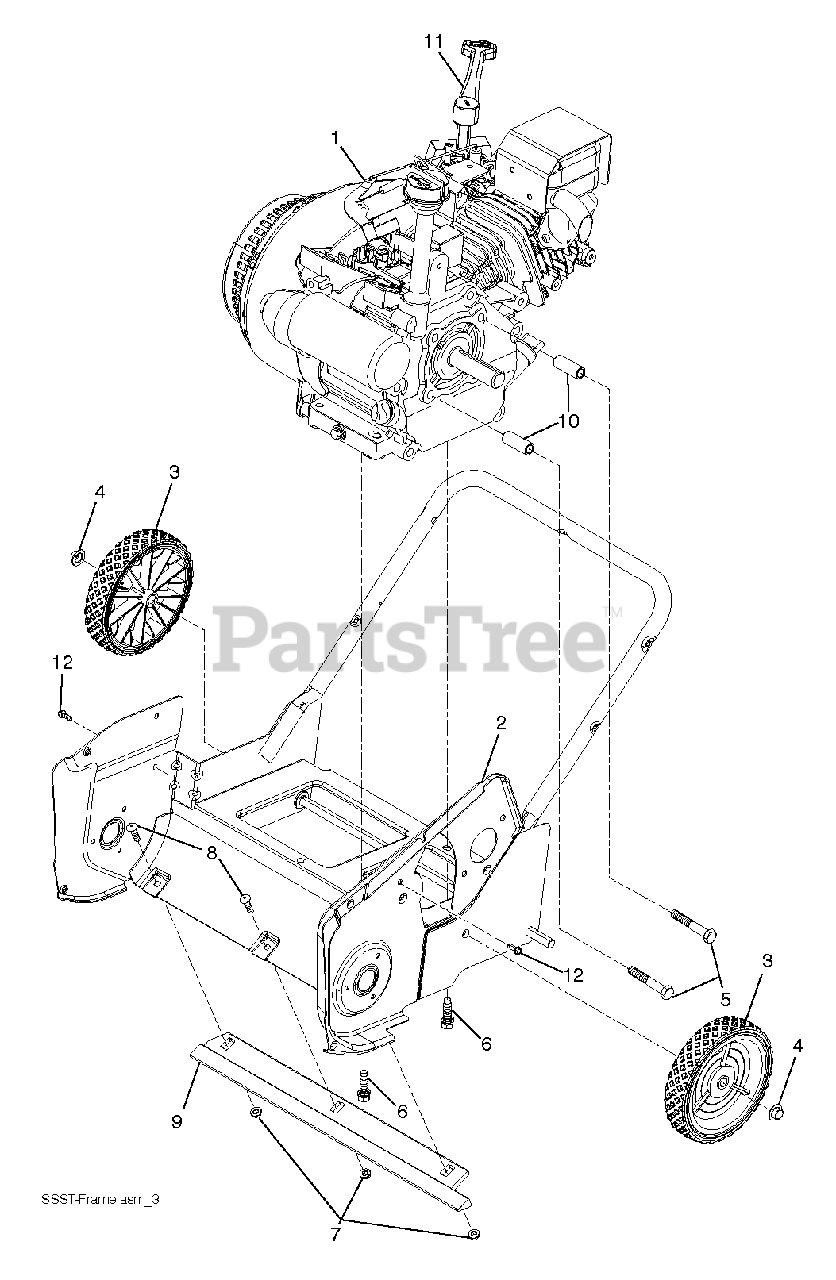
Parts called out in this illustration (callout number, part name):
1	ENGINE.LCT.136CC.SNGLE.STGE.SN
2	FRAME.WELDMENT.SNGL.STGE.BLACK
3	WHEEL.7X1.5.DMD.GS.3SPK.BLACK
4	NUT.PUSH.AXLE.0.5IN
5	SCREW. 5/16-24 X 2.00"HHCS
6	BOLT 3/8-16X1-1/8
7	NUT.HEX.FLANGE.1/4
8	BOLT.CARRIAGE.1/4-20 X 7/8
9	BAR.SCRAPER
10	SPACER.ENGINE
11	LEVER.CHOKE
12	SCREW.HX.13X.750
